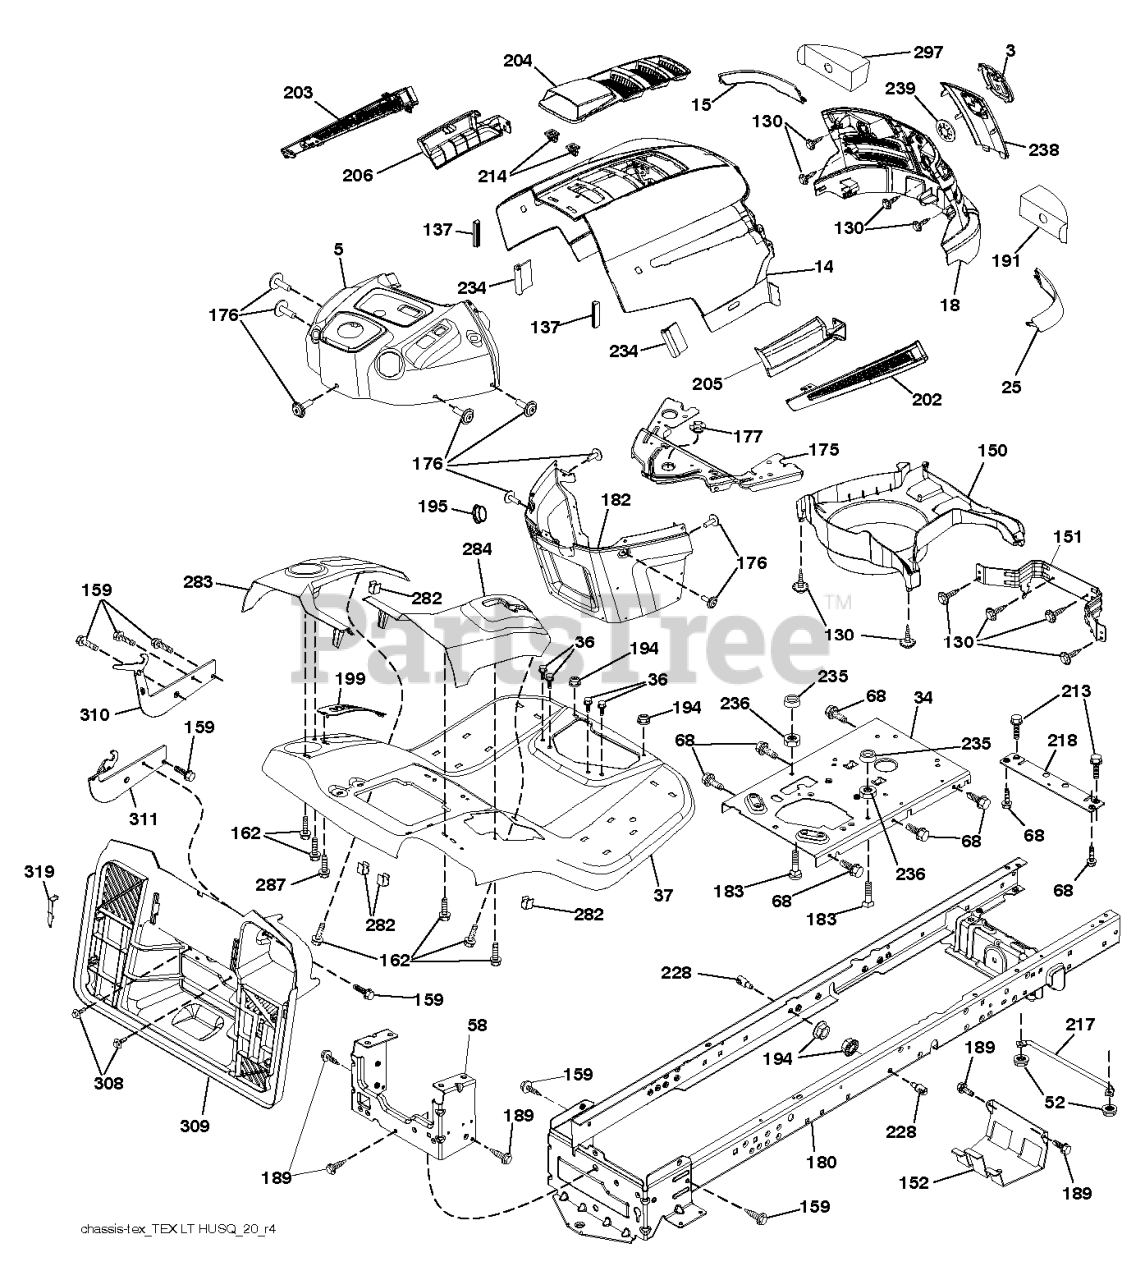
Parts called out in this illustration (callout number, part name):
3	RP LOGO
5	SUBASM.DASH.UPPER.W/BUMPER
14	HOOD.HUSQVARNA.LT.ORANGE
15	LENS.HUSQVARNA LT.RH
18	GRILLE.SVC.HUSQVARNA.GREY
25	LENS.HUSQVARNA LT.RH
34	PLATE.ENGINE.WELDED.CHASSIS
36	SCREW 5/16"
37	FENDER.TEX.SRD.CRD.BASE
52	LOCKNUT
58	DRAWBAR UPPER 2PC SMALL FENDER
68	SCREW LT
130	SCREW.#10 X 0.750.BOS
137	BUMPER DASH
151	BRACKET PIVOT
152	SHIELD.BROWNING.W/TEX
159	SCREW, 3/8-16X3/4
162	SCREW.HI-LO.CONSOLE
175	CROSSMEMBER
176	SCREW.#10-24X5/8.RN.QU
177	BUSHING STEERING
180	CHASSIS.WLDMNT.14GA.2PC.18".TI
182	DASH.LOWER.PREDATOR LT
183	BOLT.5/16-18X1-1/4 FULL THD
189	SCREW
191	INSERT.REFLECTIVE.RH.
194	NUT LOCK HEX FLANGE 5/16-18
195	PLUG.TEX.DASH.SVC.MINDER.GREY
199	PLATE DECK LIFT
202	VENT.SIDE.HUSQVARNA.LT.RT
203	VENT.SIDE.HUSQVARNA.LT.LFT
204	SUBASM.TOP.VENT.HUSQ.LT
205	SKIRT.SIDE.HUSQVARNA.LT.RT
206	SKIRT.SIDE.HUSQVARNA.LT.LEFT
213	BOLT
214	CLIP.RETAINER.TINNER.
217	ROD.PIVOT.HOOD
218	X-PIECE.HOOD.STOP.NON/
228	STUD.FASTNER.W/ANTI-ROTATE
234	BUMPER.HOOD.TEX.HUSQVARNA
235	SPACER FENDER
236	NUT.CENTERLOCK.5/16-
238	TRIM.HUSQ LT.668
282	CLIP.RETAINER.CONSOLE.LT.HUSQ
283	CONSL.DECKLIFT.LH.SRD.TEX.CRD
284	CONSL.SHIFT.GEAR.RH.SRD.GREY
287	SCREW 1/4X20
297	INSERT REFLECTIVE
308	BOLT.5/16-18UNCX3/4 W/SEMS.BLK
309	BACKPLATE.BAGGER.V2.SRD
319	BRACKET.ACTUATOR.BAGGER.SRD
